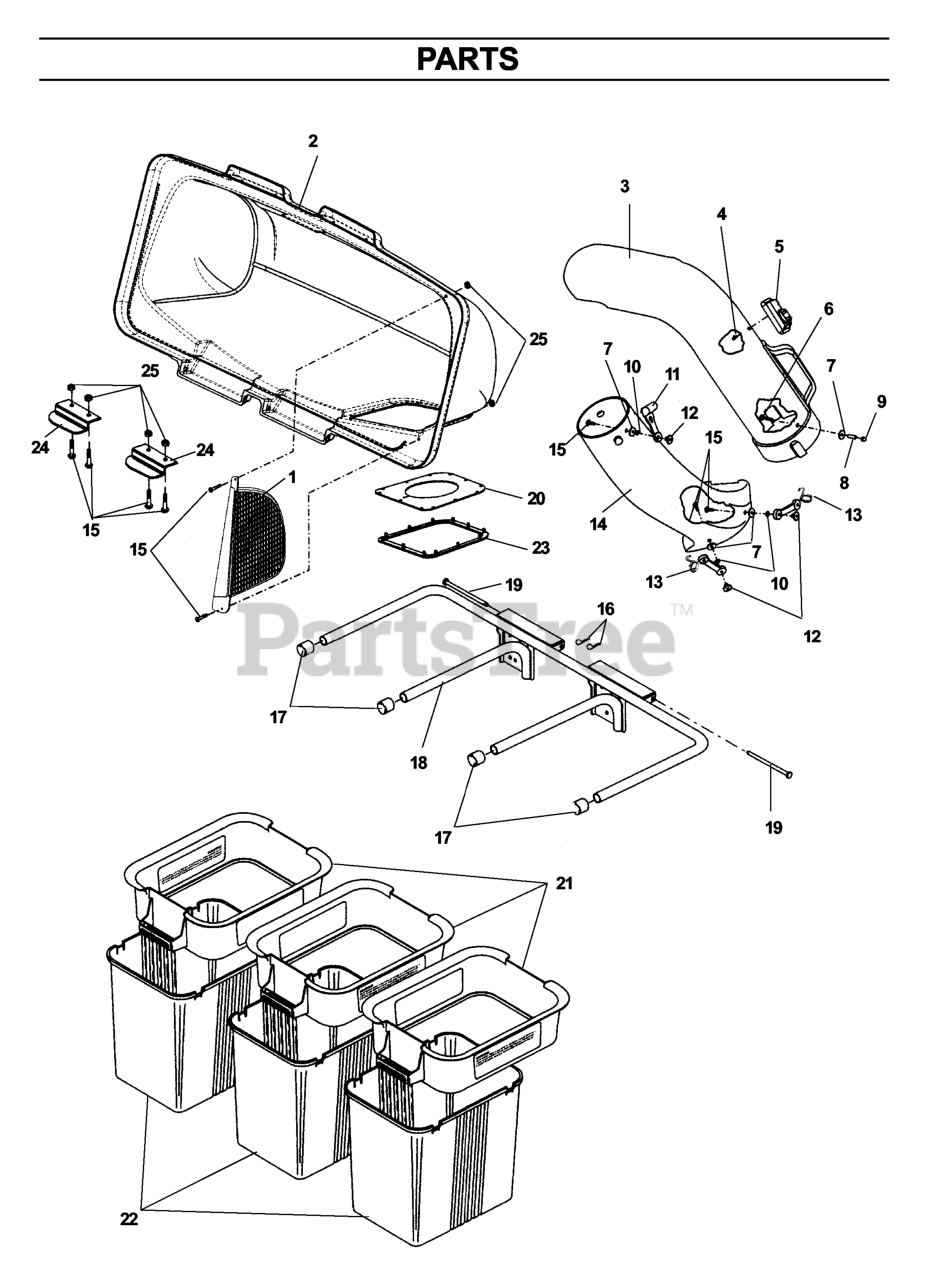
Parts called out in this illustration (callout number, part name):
1	SCREEN.COVER.BAGGER
2	COVER.ASM.3BIN.GENERIC.
3	CHUTE.COLLECTION.UPPER
4	SCREW
5	DUMP BAG INDICATOR
6	SCREW #10-24 X 1-1/8 ZD SPEC
8	BSHG .202X.75 LG SPLIT ZD SPEC
9	NUT 10-24 ACORN ZD
10	WASHER - 3/16 LOCK ZD
11	HOOD LATCH
12	NUT 10-24 WELD PLATED
13	LATCH ASSY TBR
14	LOWER CHUTE
15	SCREW #10-24 X 5/8
16	RETAINER SPRING
17	TUBING PLUG
18	BAGGER, FRAME
19	BAGGER.HINGE.PIN
20	SEAL.BAGGER.TOP.3-BIN.BLK
21	CONTAINER TOP
22	CONTAINER BOTTOM
23	GASKET.COVER.BAGGER
24	LATCH CER38
25	NUT 10-24 NYLOC
